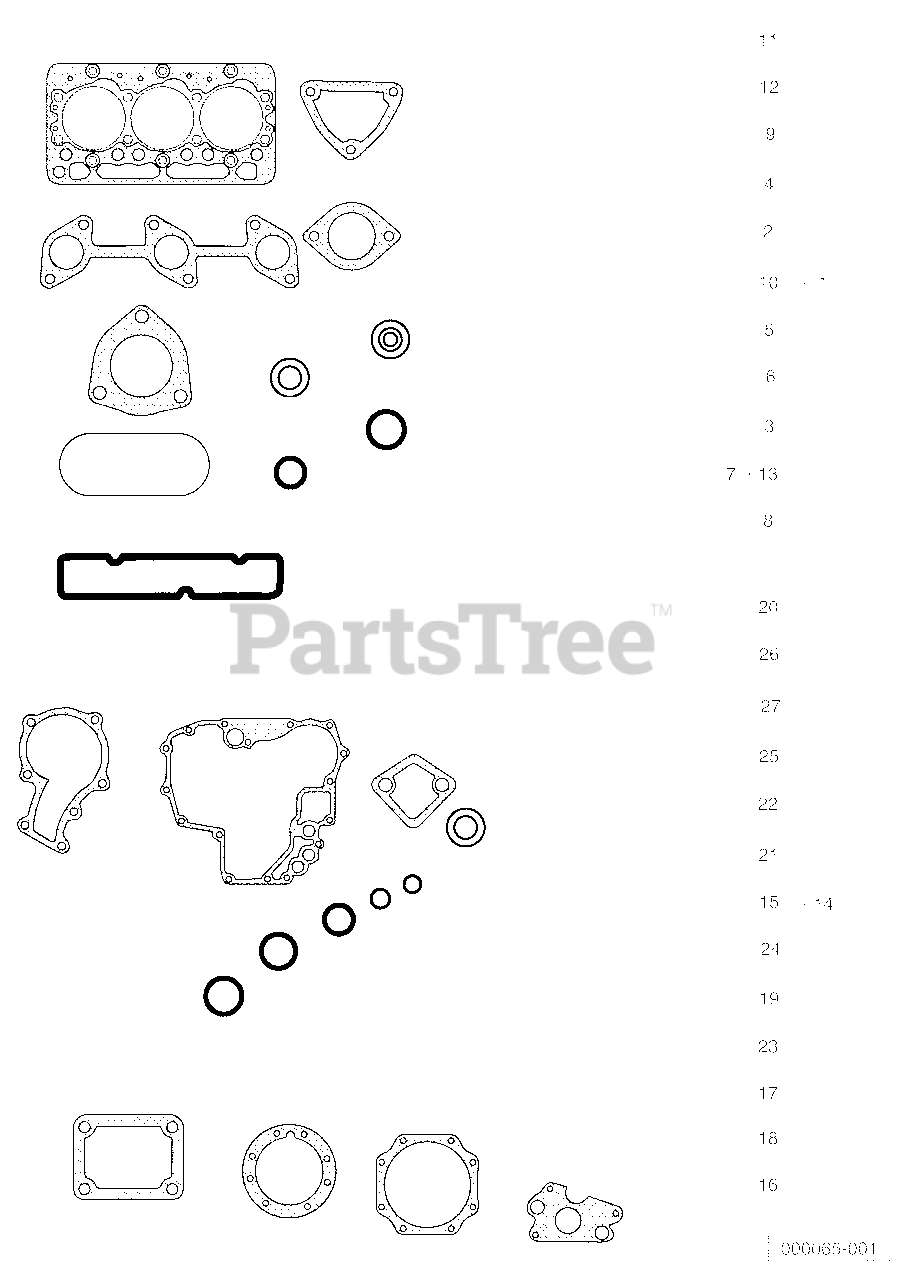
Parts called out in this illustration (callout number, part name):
1	Kit, Gasket Upper, D722
2	Gasket, Exhaust Diesel
3	O Ring, 8 X 7
4	Gasket, Thermostat
5	Gasket, 6 X 10.
6	O Ring, 30 X 36
7	Gasket, Head Cover
8	Gasket, Intake Manifold
9	Gasket, Ex-manifold
10	Seal, Valve Stem
11	Gasket, Cylinder Head
12	Gasket, Water Flange
13	Gasket, Cylinder Head Cover.
14	Kit, Gasket Lower, D722
15	O Ring, 18 X 13
16	Gasket, Oil Pump
17	Gasket, Bearing Case
18	Gasket, Cover
19	O Ring, 23 X 26
20	Gasket, Water Pump, D722
21	O Ring, 19 X 16
22	O Ring, 9 X 7
23	Gasket, Control Plate
24	O Ring, 20 X 17
25	Gasket, Idle Apparatus, Rear
26	Gasket, Gearcase, D722.
27	Gasket, Fuel Pump, D722
